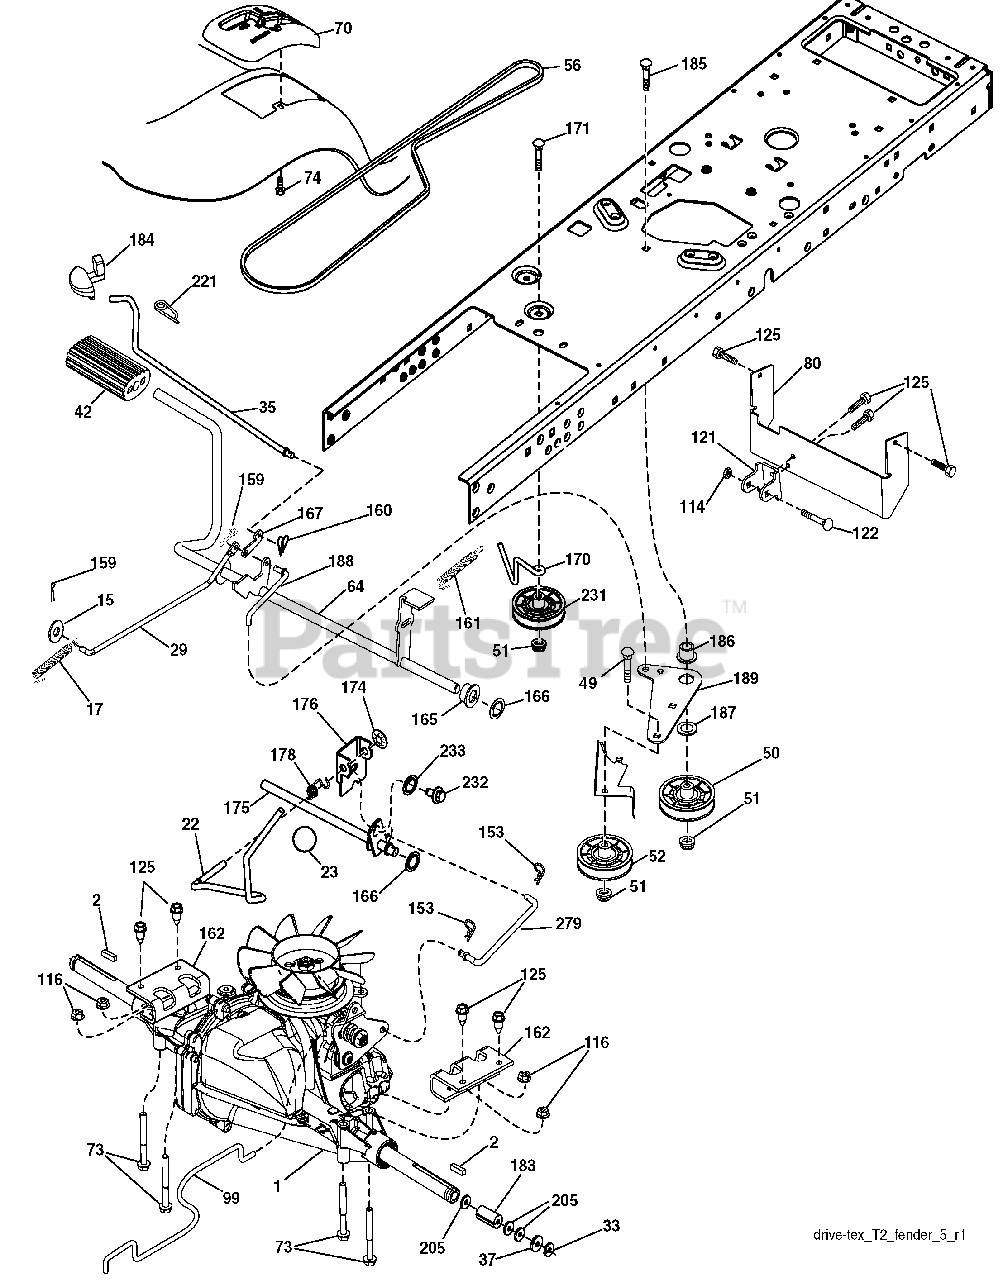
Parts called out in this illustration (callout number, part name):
1	Transaxle, Hydro Gear T2 (See Transaxle Breakdown)
2	Key Square
15	Washer 13/32 x 13/16 x 16 Ga.
17	Spring, Brake
22	Rod Shift
23	Knob
29	Rod, Brake
33	Ring E
35	Rod, Brake, Park
37	Washer 25/32 x 1-1/4 x 16 Ga.
42	Cover, Foot Pedal
49	Bolt
50	Pulley Idler Flat
51	Lock Nut 3/8-16
52	Idler V-Groove 910" Offset
56	V-Belt, Drive
64	Shaft Asm. Pedal Brake Control
70	Console
73	Bolt Hex 5/16-18 Gr. 5
74	Screw 1/4 x 1/2
80	Strap Torque
99	Rod Spring Bypass
114	Nut Lock 5/16-18 unc
116	Nut Lock Hex Flange 5/16-18
121	Bracket Strap Torque
122	Bolt 5/16-18 x 2.50
125	Screw 5/16-18 x 3/4
153	Retainer Spring 1"
159	Pin Cotter 1/8 x 3/4
160	Retainer Clip
161	Spring, Return, Clutch
162	Adapter Transaxle
165	Bushing
166	Nut Push .625
167	Latch Brake Parking
170	Keeper Belt Centerspan
171	Bolt
174	Nut Push
175	Shaft Asm Shift
176	Arm Clevis Rod Shift
178	Spring Shift
183	Spacer Axle
184	Handle Parking Brake
185	Bolt
186	Spacer Retainer
187	Washer
188	Link Clutch Ground Drive
189	Bellcrank Ground Drive
190	Keeper Bellcrank Ground Drive
205	Washer 25/32 x 1-5/8 x 16 Ga.
221	Retainer Spring Clip Handle
231	Idler V-Groove 1.688" Offset
232	Bolt 7/16-14 x 1 Gr 5
233	Washer Serrated
279	Link Shift
